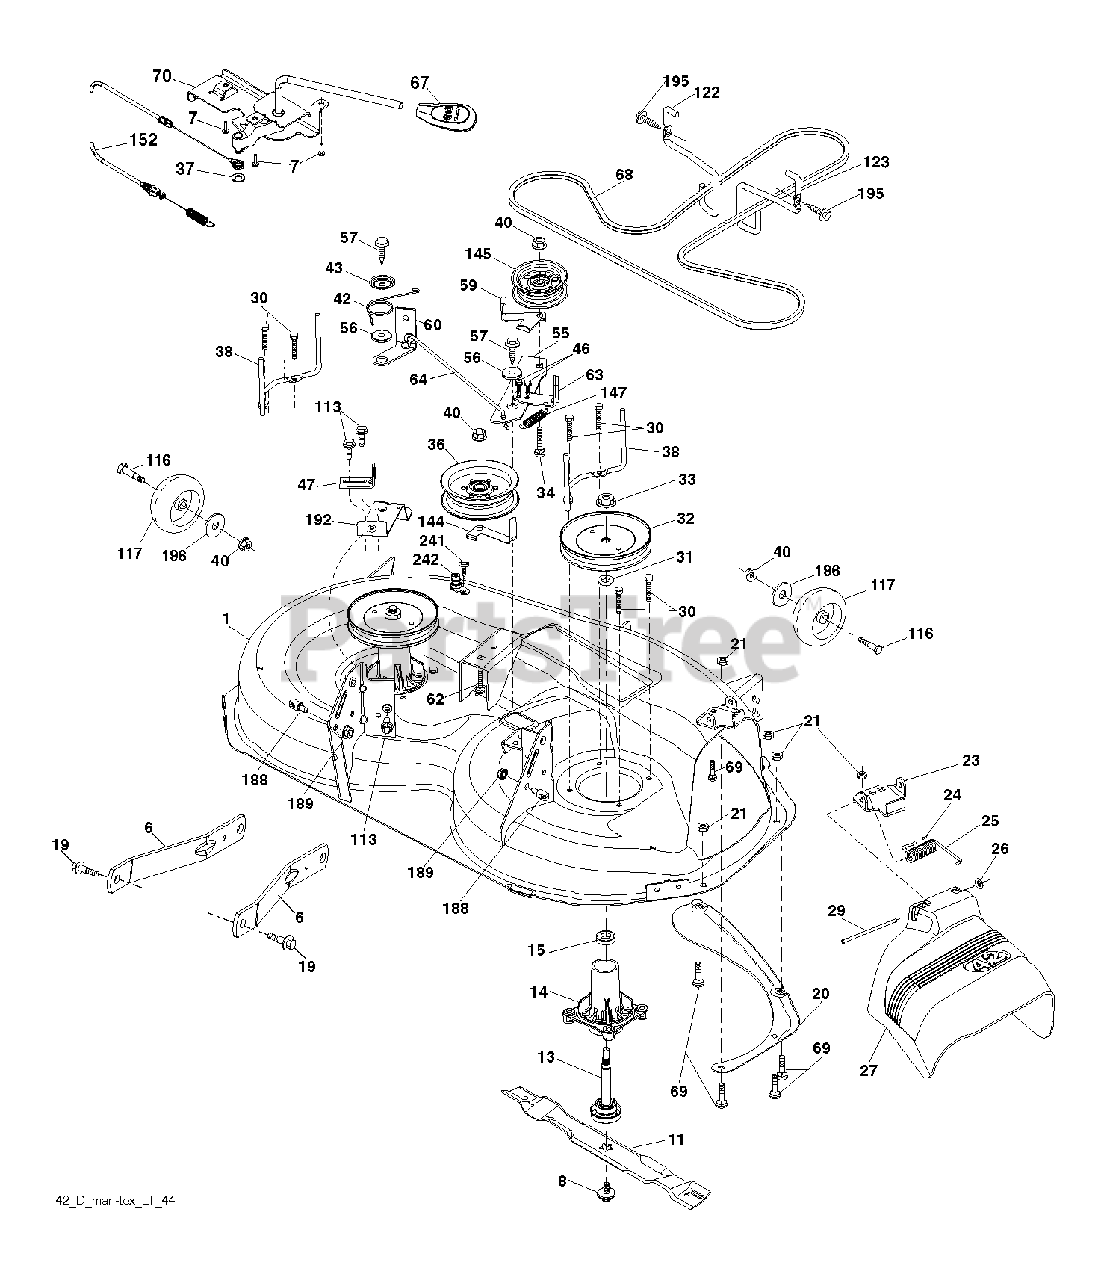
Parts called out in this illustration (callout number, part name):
1	DECK SVC 42" 2GWB 419175X668
6	ARM.SUSPENSION.MOWER.R
7	SCREW.#10 X 0.750.BOS
8	BOLT.WASHER.ASM.7/16-2
11	42" HI-LIFT BLADE
13	SHAFT.ASM.MDRL.N/GREASE.38
14	HOUSING.MANDREL.4PT.
19	BOLT.SHOULDER
20	BAFFLE.VORTEX
21	LOCKNUT
23	BRKT.DEFLECTOR.38"2005+
24	CAP-SLEEVE LT
25	SPRING.TORSION.DEFLECT
26	NUT PUSH M
27	SHIELD.DEFLECTOR.MOWER.42"BLAC
29	ROD.HINGE
30	SCREW, WASHER HEAD
31	WASHER.SPACER.MANDREL
32	PULLEY.MANDREL.5.438.PD
33	NUT.FLANGE.LOCK.TOP
34	BOLT.3/8-16X1.50
36	PULLEY.IDLER.2006
37	WASHER
38	KEEPER.BELT.MANDREL.PULLEY
40	NUT LOCK FLG 3/8-16 UNC
42	SPRING.TORSION.BRAKE
43	SRPING.TORSION.RETAINE
46	SCREW.1/4-20X5/8
47	BRKT.CLUTCH.CABLE
55	IDLER.ARM.42"
56	SPACER.RETAINER
57	SCREW 3/8-16X1
59	GUARD, BELT
60	ARM BRAKE MOWER
63	ARM BRAKE MOWER
64	LINKAGE.BRAKE.ASM.ZINC
67	HANDLE.CLUTCH.CABLE.LT
68	BELT.DECK.DRIVE.42"
69	BOLT
70	CLUTCH.ASM.MANUAL.YT.PREDATORQ
113	BOLT.5/16HEX.WHS.HD
116	BOLT.SHOULDER.3/8-16X3-5/8.
117	WHEEL. GUAGE RALLY
122	KEEPER BELT ENGINE LH
123	KEEPER BELT RH
144	KEEPER.BELT.MOWER
145	PULLEY.IDLER.48"PRIMARY
147	RETURN SPRING
152	CABLE.CLUTCH.CABLE.W/SPRING
188	STUD.FASTNER.W/ANTI-ROTATE
189	NUT LOCK HEX FLANGE 5/16-18
192	BRKT.BRAKE.STAND.LH.
195	SCREW, 3/8-16X3/4
196	WASHER
241	SCREW.TT.#10-32X.5.3/8.FLANGE
242	PORT.WASHOUT
